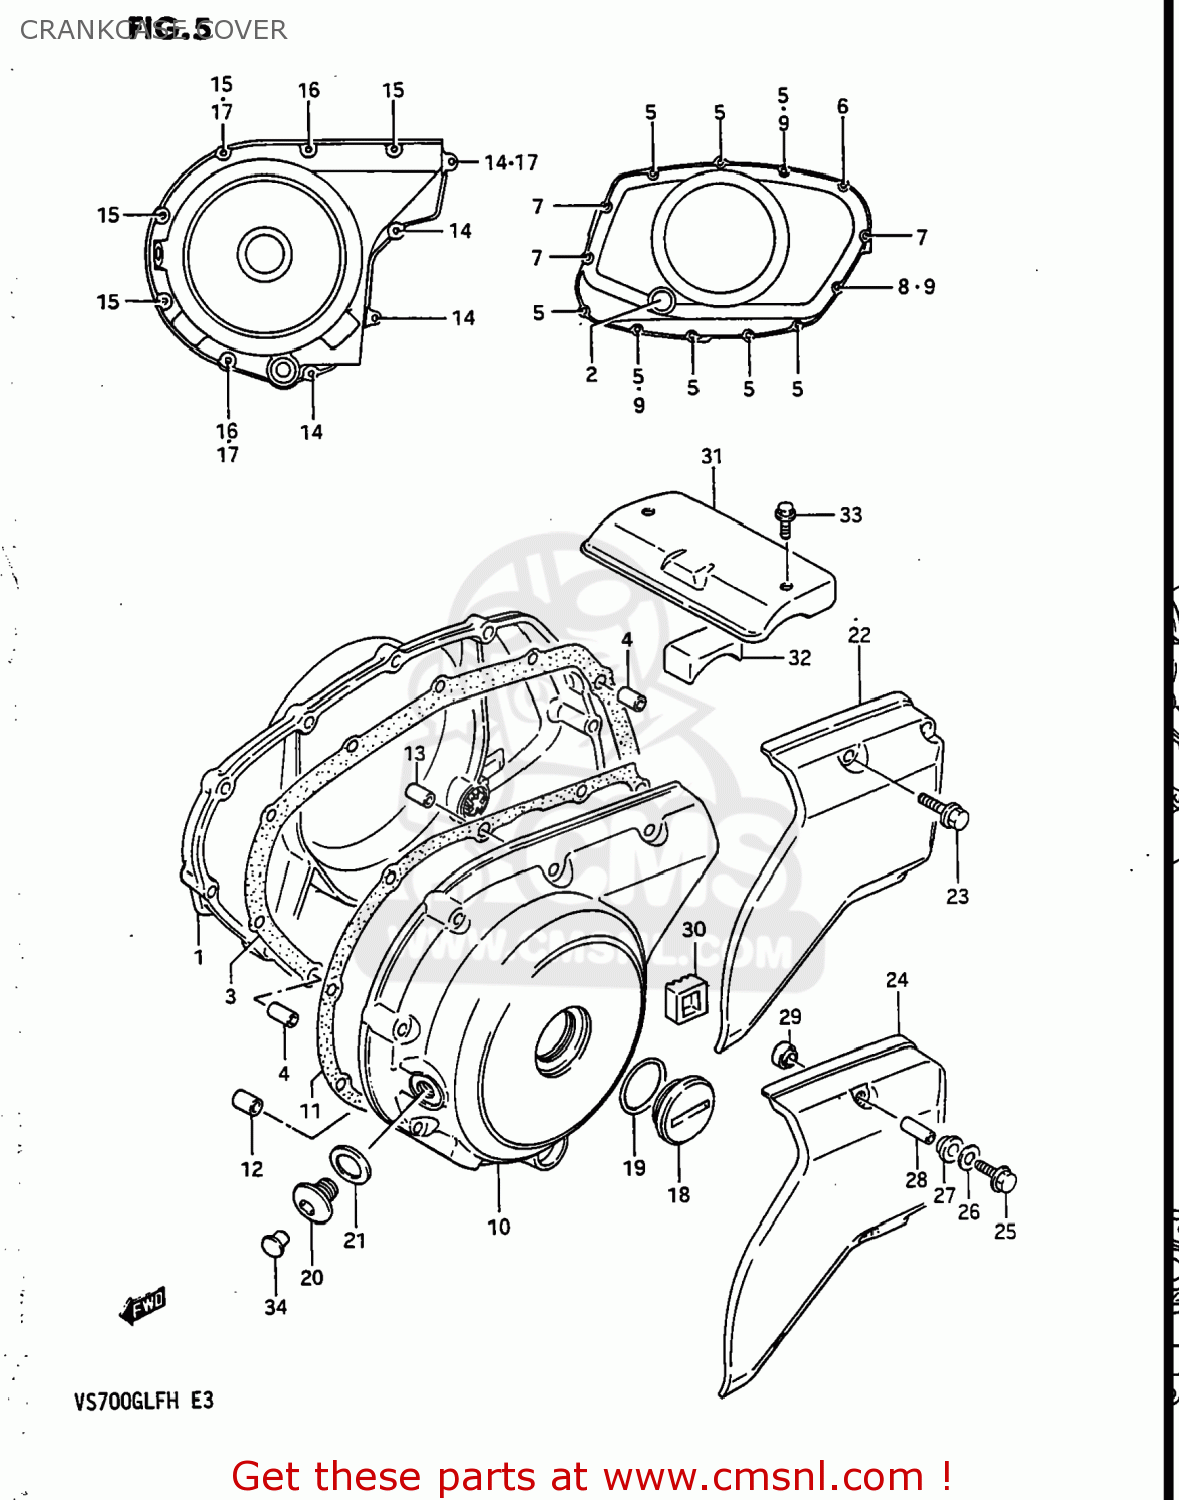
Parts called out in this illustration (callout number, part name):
1	COVER,CLUTCH
2	LENS,OIL LEVEL CHECK
3	GASKET,CLUTCH COVER (NAS)
4	PIN
5	BOLT
6	BOLT
7	BOLT
8	BOLT
9	GASKET(5.8X13X1.2) (NAS)
10	COVER
11	GASKET,MAGNETO COVER (NAS)
12	PIN (11X20)(SUS)
13	PIN
14	BOLT (6X30)
15	BOLT
16	BOLT
17	GASKET(5.8X13X1.2) (NAS)
18	Chrome Crankshaft Plug
19	O RING(D:3.1,ID:32.7)
20	PLUG,14X12
21	GASKET(14X19.2X2) (NAS)
22	COVER,SECONDARY DRIVE
23	BOLT
24	COVER,SECONDARY GEAR CASE
25	BOLT
26	WASHER
27	WASHER(8.7X15X2.1)
28	SPACER
29	WASHER(8.7X16X5)
30	DAMPER,SECONDARY COVER
31	COVER,STARTER MOTOR
32	DAMPER,MOTOR COVER
33	BOLT
34	CAP(OD:12)
